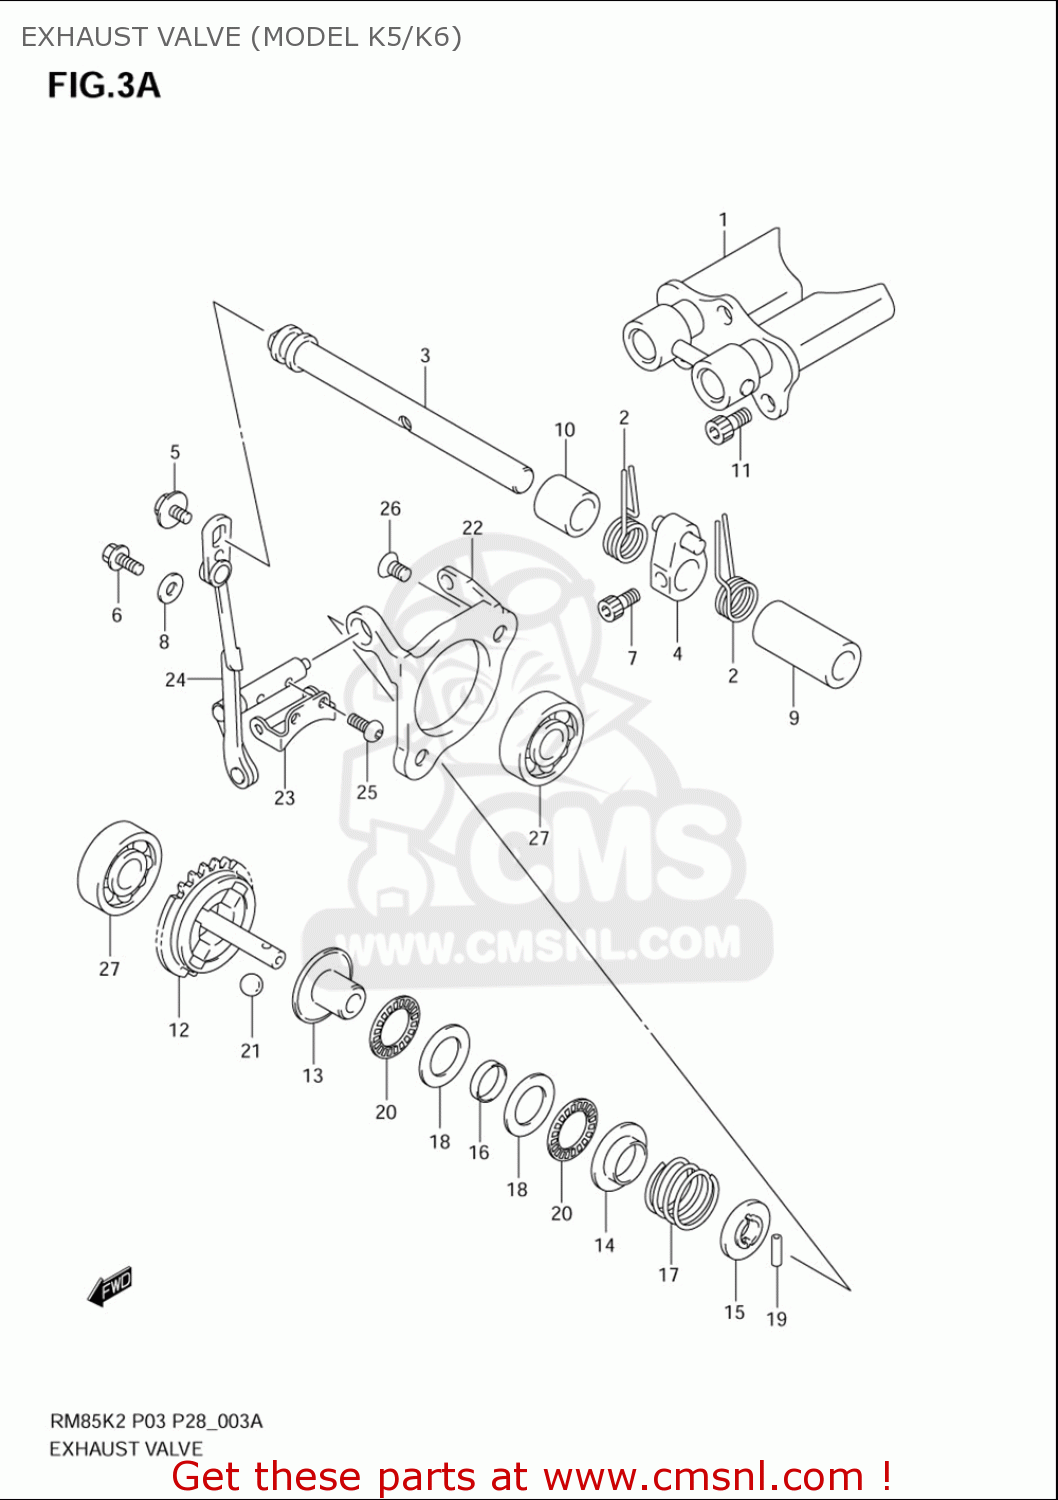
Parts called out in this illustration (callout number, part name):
1	VALVE ASSY,EXHAUST VALVE
2	SPRING,EXHAUST VALVE SHAFT ARM
3	SHAFT,EXHAUST VALVE
4	ARM,EXHAUST VALVE SHAFT
5	BOLT(5X10)
6	BOLT(6X10)
7	BOLT(4X8)
8	WASHER(6.5X15X1.6)
9	SPACER(8.4X12X13)
10	SPACER(8.5X12X11)
11	BOLT
12	GOVERNOR SET,EXHAUST
13	GOVERNOR,DRIVEN
14	STOPPER,GOVERNOR SPRING NO.1
15	STOPPER,GOVERNOR SPRING NO.2
16	SPACER,GOVERNOR
17	SPRING,GOVERNOR
18	SHIM(15X28X1)
19	ROLLER(3X12.5)
20	BEARING(15X28X2)
21	BALL
22	BASE,ACTUATOR
23	ARM,ACTUATOR
24	ACTUATOR,EXHAUST VALVE
25	BOLT(4X8)
26	SCREW(5X10)
27	BEARING(8X22X7)
